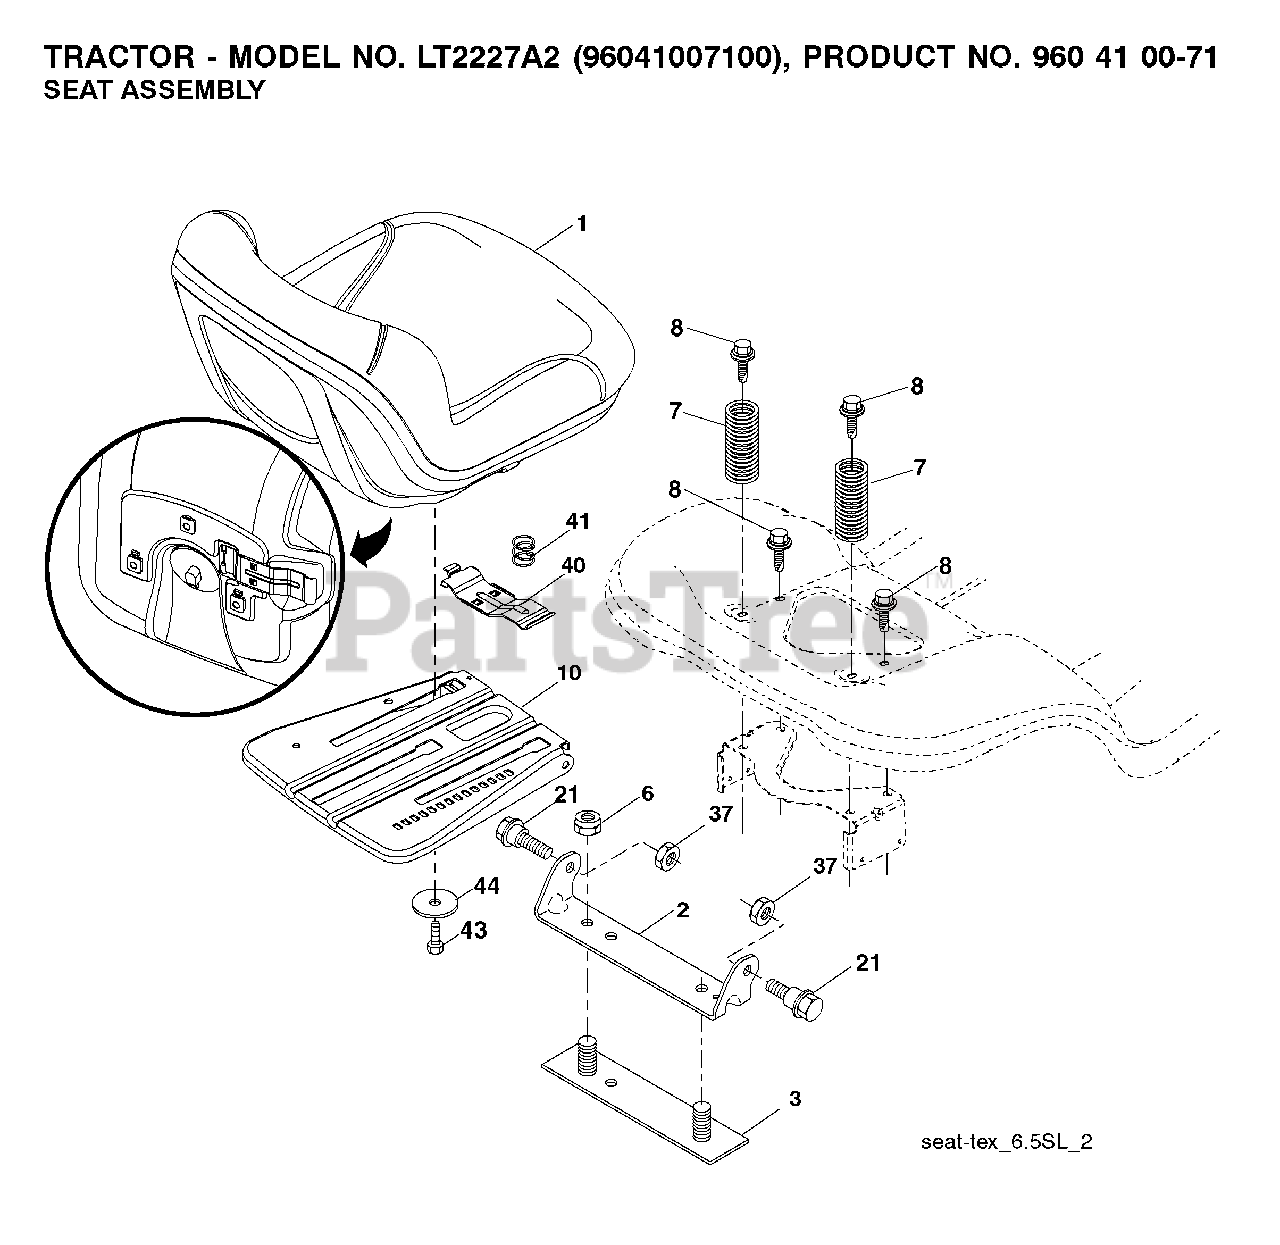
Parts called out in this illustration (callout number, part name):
1	SEAT.TG150.BLK.NLOGO.
2	BRKT.PIVOT.FENDER
6	NUT
7	SPRING COMPRESSION
8	BOLT, 5/16-18 X 1 3/4
10	PAN.ASM.SEAT.3PT
21	BOLT.SHOULDER.5/16-18
37	NUT.71038.31-18.HEX.NYLOCK
40	HANDLE.SLIDE.SEAT.TEX.BLACK
41	SPRING.LATCH.SEAT.TEX
44	WASHER 13/32 X 2-3/8 X 12GA
